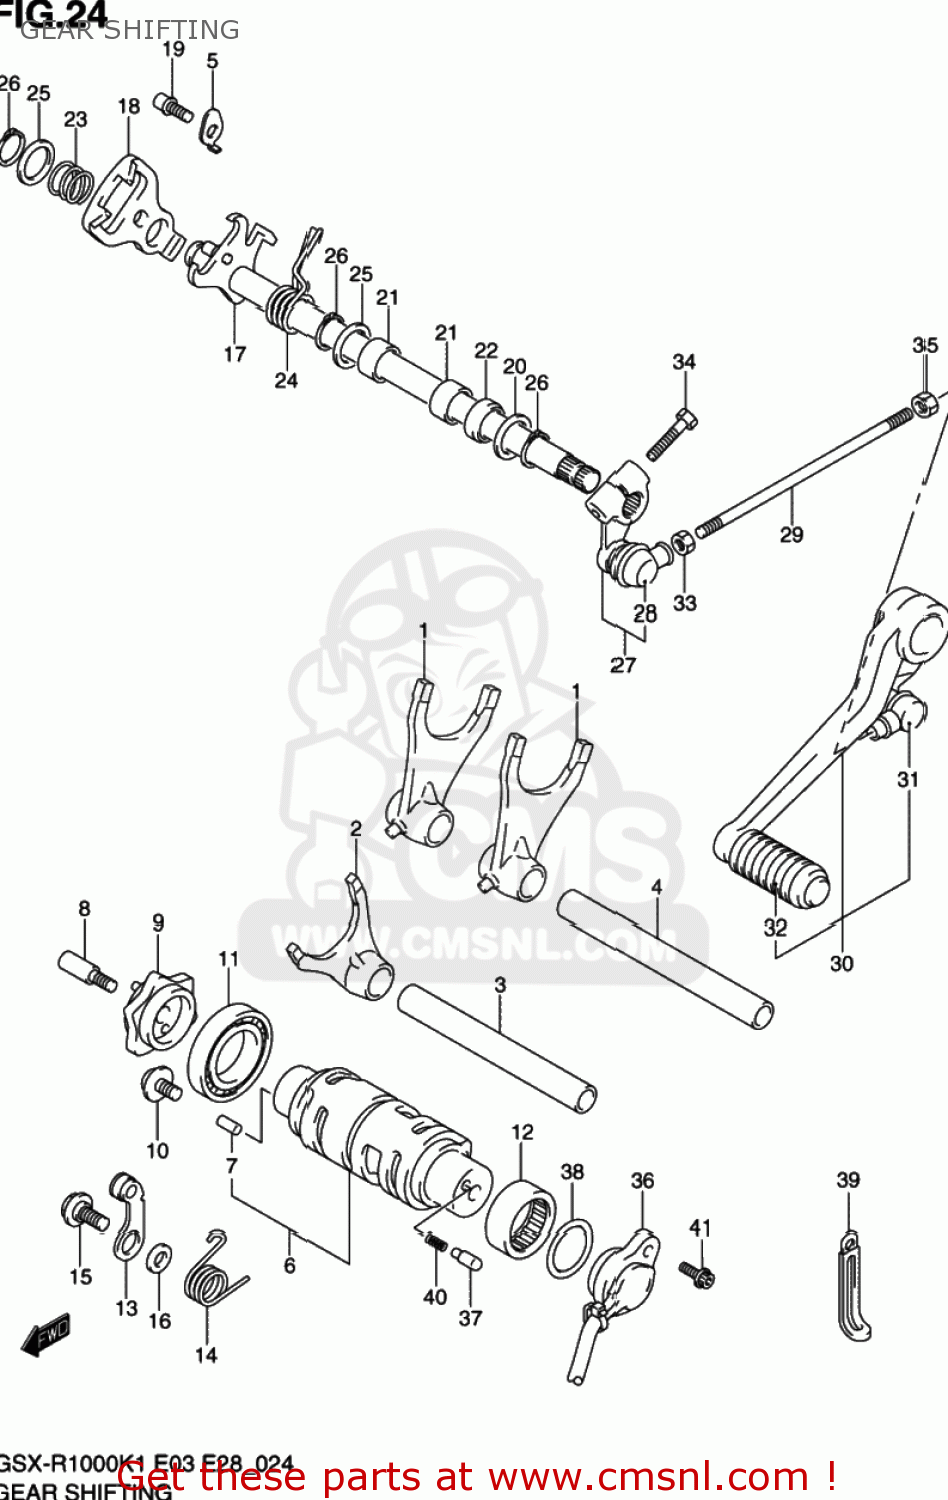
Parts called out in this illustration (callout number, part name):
1	FORK,GEAR SHIFT NO.1
2	FORK,GEAR SHIFT NO.3
3	SHAFT,GEAR SHIFT FORK
4	SHAFT,SHIFT FORK NO.2(L:132)
5	RETAINER,GEAR SHIFT FORK SHAFT
6	CAM,GEAR SHIFT
7	PIN
8	BOLT,GEAR SHIFT CAM PL
9	PLATE,GEAR SHIFT CAM
10	SCREW(6X12)
11	BEARING(25X47X8)
12	BEARING(25X32X12)
13	STOPPER,SHIFT CAM
14	SPRING,SHIFT
15	BOLT(6X14.3)
16	WASHER
17	SHAFT,GEAR SHIFT
18	PLATE,GEAR SHIFT CAM DRIVE
19	STOPPER,GEAR SHIFT ARM
20	WASHER(14X29X0.8)
21	BEARING(14X20X12)
22	SEAL,OIL(14X22X6)
23	SPRING
24	SPRING
25	SHIM(14X22X1)
26	CIRCLIP
27	ARM,GEAR SHIFT LINK
28	COVER,DUST
29	ROD,GEAR SHIFT LINK
30	LEVER ASSY,GEAR SHIFT
31	COVER,DUST
32	RUBBER,GEAR SHIFT PEDAL
33	NUT
34	BOLT
35	NUT
36	BASE ASSY,GEAR SHIFT TERMINAL
37	PIN(5X15.5)
38	O RING(D:2.4,ID:25.7)
39	CLAMP(L:65)
40	SPRING
41	BOLT
